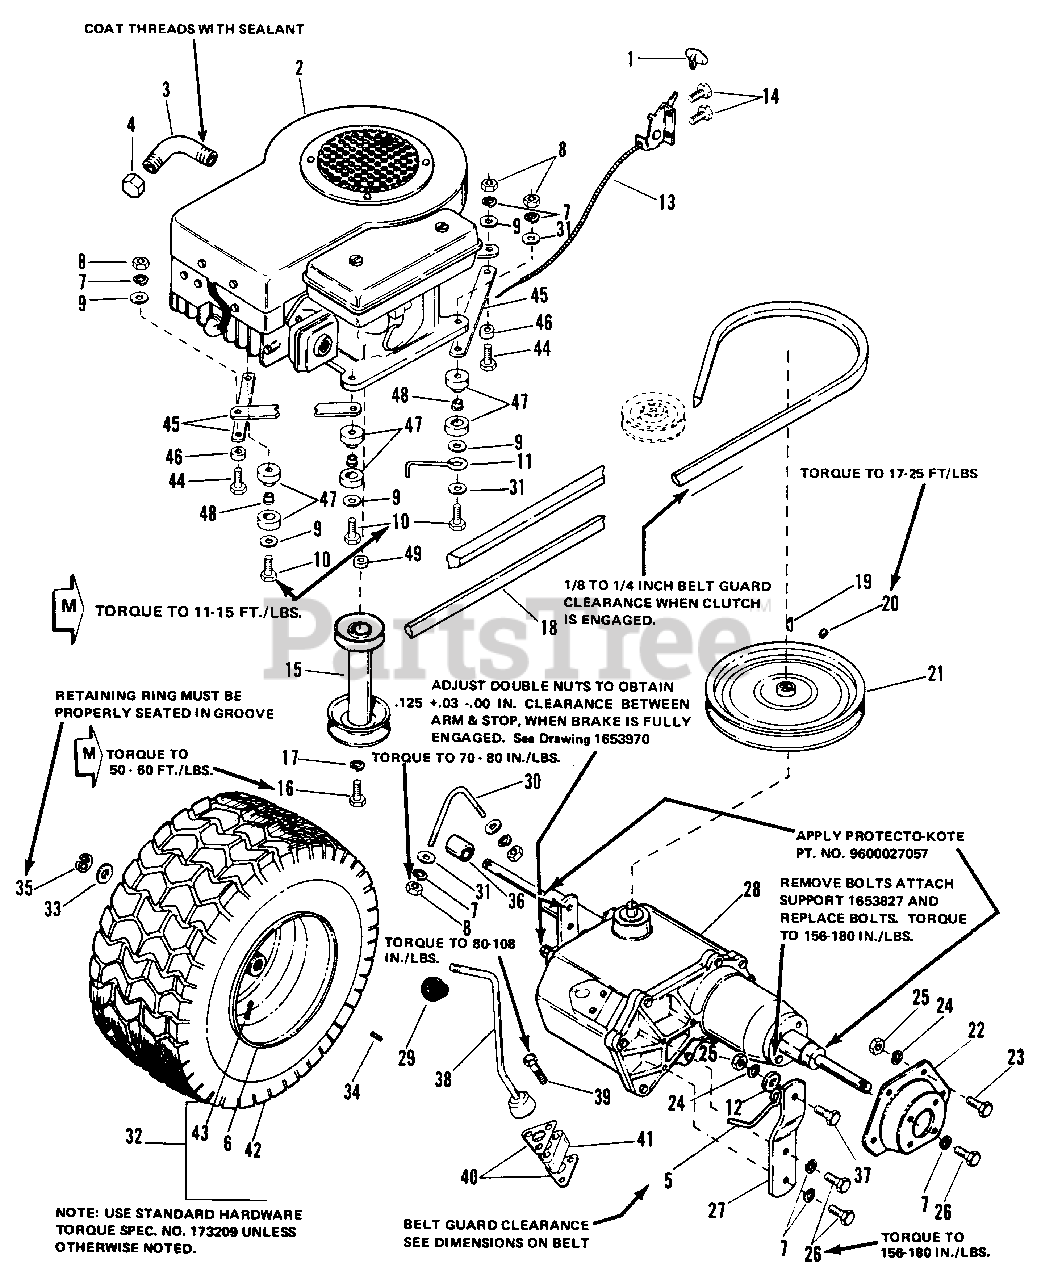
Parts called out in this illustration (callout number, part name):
1	KNOB
2	ENGINE, (Manual Start) B/S Model
4	CAP, Pipe 3/4
7	LOCKWASHER, 5/16
8	NUT, Hex Full, 5/16-18
9	WASHER, Plain 5/16
10	CAPSCREW, Hex Hd., 5/16-18 x 3
12	WASHER, Plain
13	CONTROL, Throttle
14	SCREW, Taptite, 1/4-20 x 3/4
15	PULLEY, Engine
16	CAPSCREW, 7/16-20 x 1 1/4
17	LOCKWASHER, 7/16
18	V-BELT, Arbor Drive, 50"
19	KEY
20	SETSCREW, 5/16-18 x 1/2
21	PULLEY, 10"
22	SUPPORT, Axle, L.H.
23	CAPSCREW, 3/8-16 x 3/4
24	LOCKWASHER, 3/8
25	NUT, Hex 3/8-16
26	CAPSCREW, 5/16-18 x 1
27	SUPPORT, Strap
28	TRANSAXLE
29	KNOB
30	BOLT, Axle
31	WASHER, Plain 5/16
32	WHEEL & TIRE
34	KEY
35	RING, Retaining
37	CAPSCREW, 3/8-16 x 1 1/4
38	LEVER, Shift
39	SCREW, Washer head,1/4-20 x 1 3/4
40	GASKET
41	BLOCK, Riser
43	VALVE STEM & CAP
44	CAPSCREW, 5/16-18 x 1 1/4
47	MOTOR MOUNT
48	BUSHING, Engine Mount
